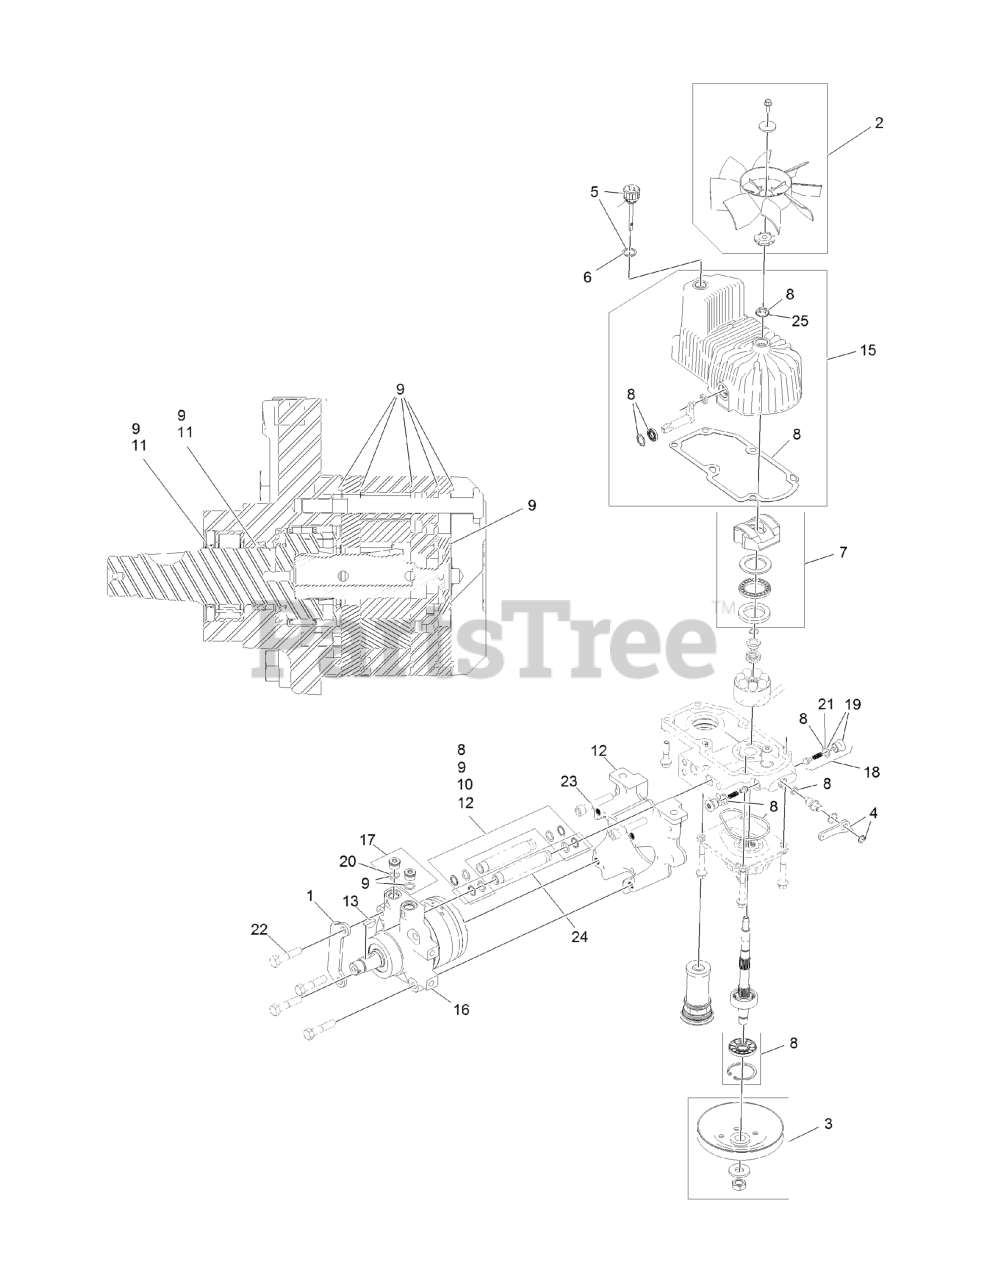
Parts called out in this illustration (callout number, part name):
1	MOUNT-SHOE, HORSE
2	FAN KIT
3	PULLEY KIT
4	HANDLE-BYPASS VALVE, HYDRO
5	DIPSTICK-HYDRO W/GASKET
6	GASKET-DIPSTICK, HYDRO
7	SWASH BLOCK KIT
8	PUMP SEAL KIT
9	MOTOR SEAL KIT
10	TUBE SEAL KIT
11	OUTPUT SHAFT SEAL KIT
12	NOSE CUP-UHT
13	KEY-WOODRUFF
15	HOUSING-HYDRO, RH
16	MOTOR-HYDRAULIC RH 240CC
17	MAGNETIC PLUGS SERVICE KIT
18	CHECK VALVE ASM
19	PLUG-CHECK (W/O-RING)
21	O-RING-CHECK VALVE
22	SCREW HH
23	SCREW-HSH
24	HYDRAULIC TUBE KIT
25	SEAL-FAN DRIVE
26	Kit, Pump Section 12Cc RH
27	KIT, ROTATING GRP 12CC RH
